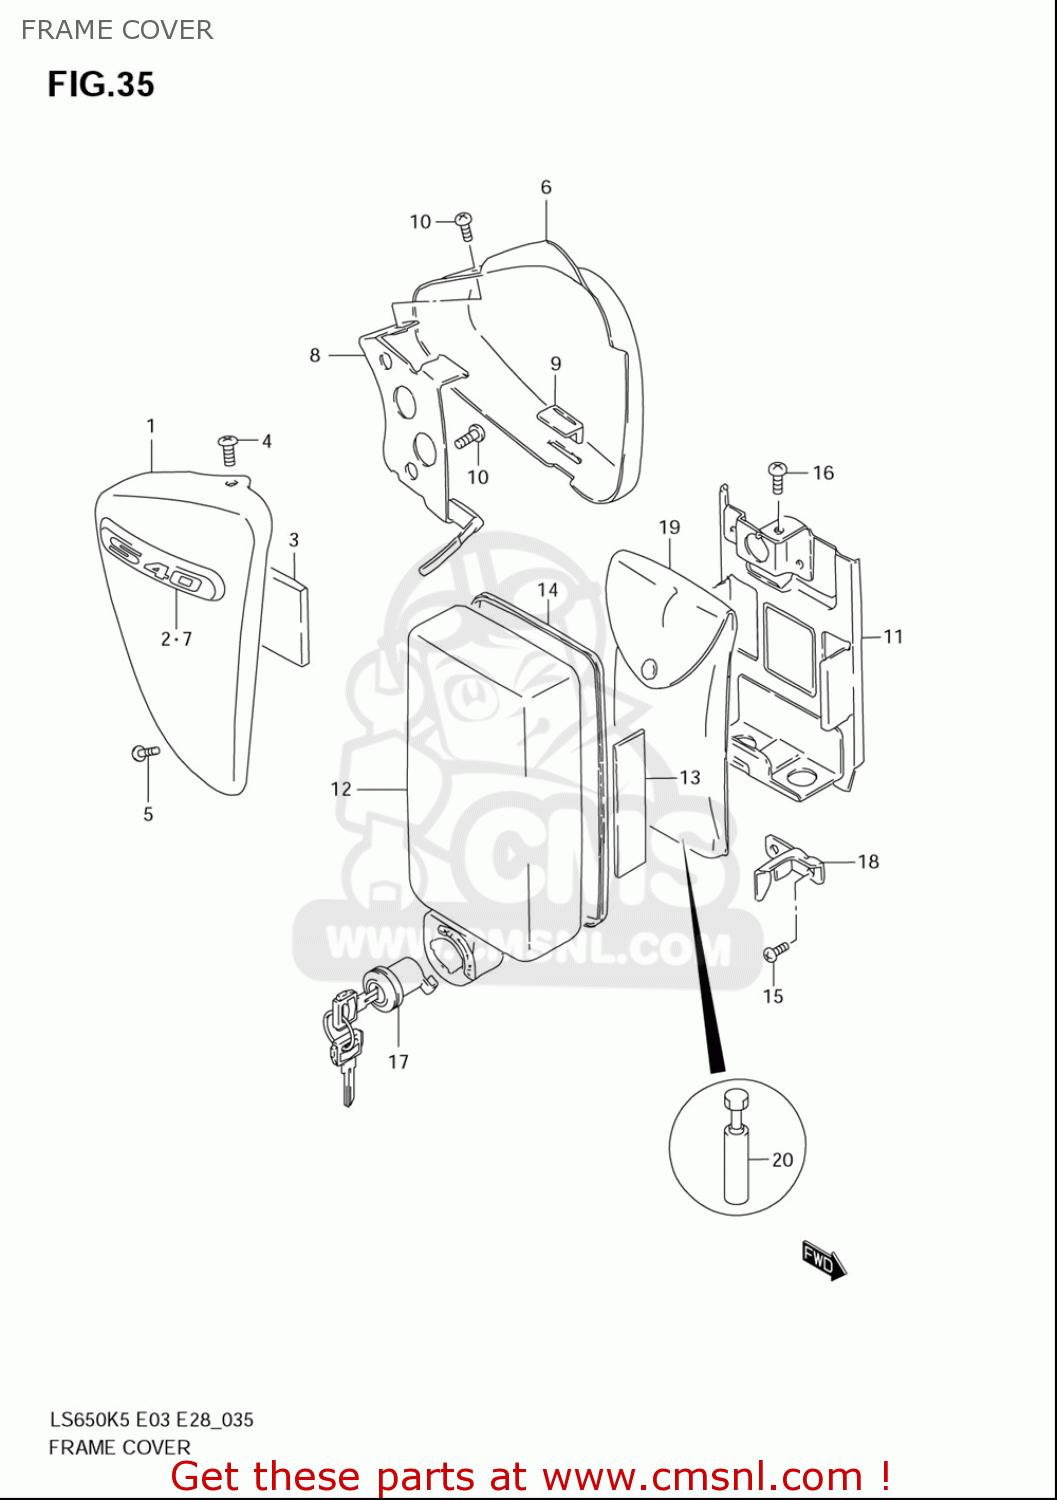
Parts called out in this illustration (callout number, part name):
1	COVER, FRAME RH (WHITE)
2	EMBLEM,FRAME COVER
3	PAD
4	SCREW
5	SCREW
6	COVER ASSY,FRAME,L(WHITE)
7	EMBLEM,FRAME COVER
8	BRACKET,FRAME COVER,L
9	CUSHION,FRAME COVER
10	SCREW
11	HOLDER,TOOL
12	COVER,TOOL HOLDER
13	PROTECTOR(80X80X2)
14	MOLDING
15	SCREW
16	SCREW
17	LOCK SET,TOOL HOLDER
18	PLATE,TOOL HOLDER LOCK
19	TOOL ASSY
20	GAUGE ASSY,TENSION
